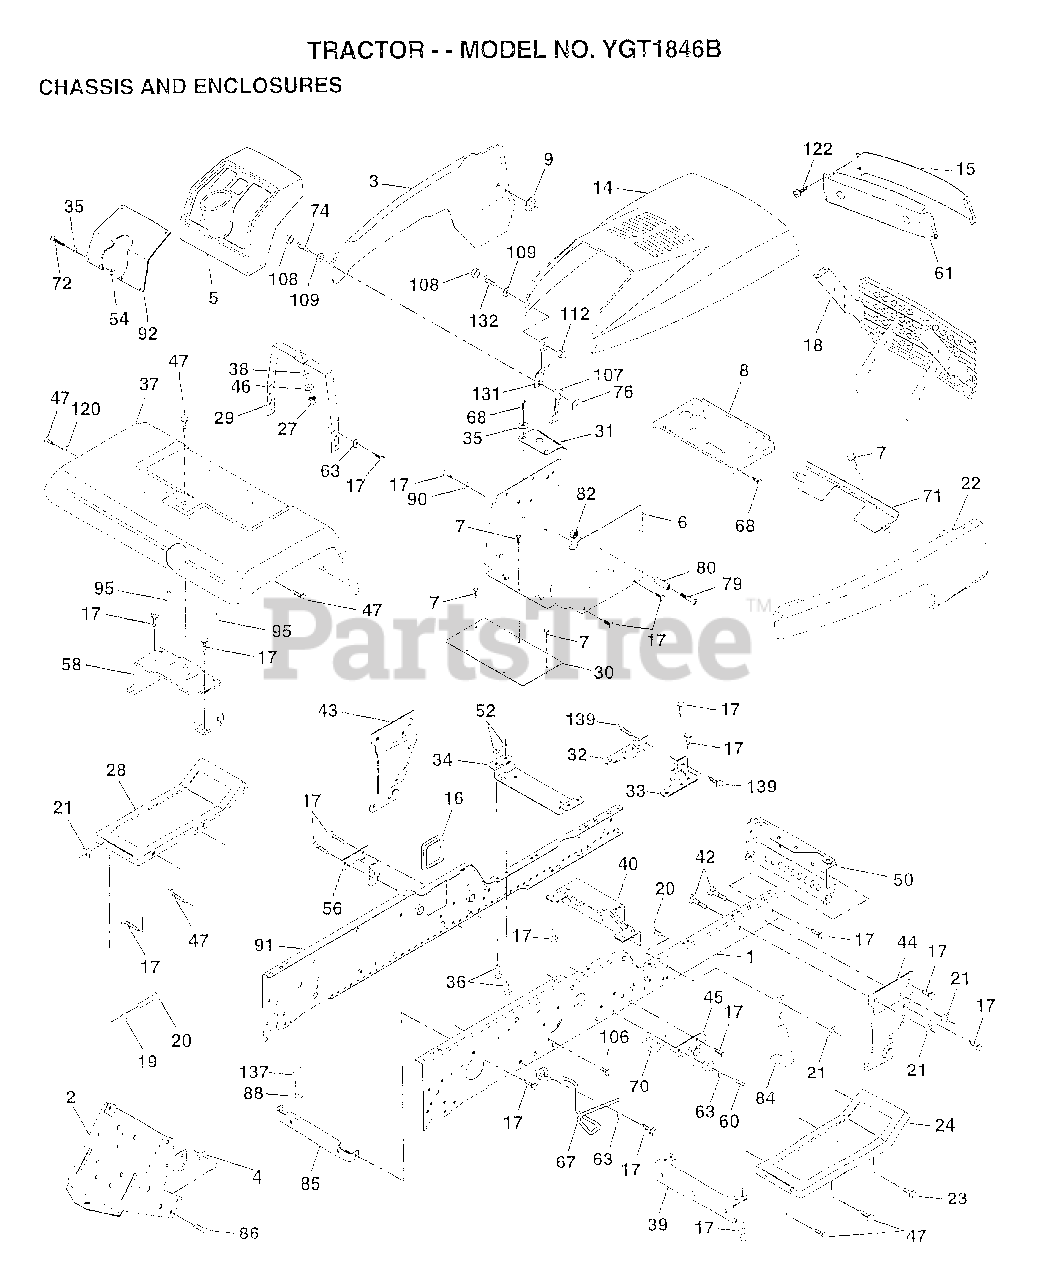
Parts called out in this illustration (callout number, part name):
1	"RAIL,FRAME RH"
2	DRAWBAR GT
3	"PANEL ASM-SIDE,LH"
4	NUT.7/16
5	DASHBOARD BLACK
6	DASH LOWER
7	SCREW
8	SUPPORT.DASH.BTRY
9	PAL NUT LT
14	"HOOD, YARD PRO"
15	LENS.BAR.CLEAR
16	COVER ACCESS
17	SCREW
19	WASHER
20	BOLT
22	"PANEL ASM SIDE,RH"
23	SCREW GTV
24	FOOTREST.RH.LT/GT
28	FOOTREST PNT LH
29	DASH.SUPT.YP/HUSQ
30	SADDLE.SCR.6SP
31	BRKT SUPT 1-PC VG
32	BKRT.PIVOT.CHASSIS.RH
33	BKRT.PIVOT.CHASSIS.LH
34	BRACKET.ENG.SUPT.
35	WASHER
36	BOLT
38	LOCKWASHER
39	BRACKET.AXLE.FRT.
40	"BRKT SUPPORT,AXLE"
43	BRACKET.SUS.FT.LH
44	BRACKET.SUS.FT.RH
45	BRACKET.SUSP.RH.
46	WASHER PM
47	SCREW LT
50	"BRKT CHASSIS,FRNT"
52	NUT
56	BRACKET.SUSP.LH.
58	BRKT.ASM.FENDER
60	SCREW
61	BEZEL.1 PC
63	WASHER
67	"GUIDE BELT, T/A"
68	SCREW LT
70	GUIDE.BELT.MID.SP
72	SCREW
74	SCREW
76	WELDNUT
79	SCREW
80	SPACER LT
84	STOP.OVER.CENTER
85	BRACKET.SUPT.TRAN
86	BOLT
88	LOCKWASHER
90	LOCKWASHER
91	"RAIL FRAME,LH"
95	NUT-PUSH YT
107	HOOD LATCH T
108	SNAP CAP LT
109	WASHER LT
112	ACORN NUT RB
120	WASHER HYT
122	SCREW.HEX.WS.HD
131	BKT.SPT.HOOD/PANL
132	SCREW.10-24X3/8.
137	BOLT.FIN.HEX.
139	BOLT.SHOULDER.5/16-18
